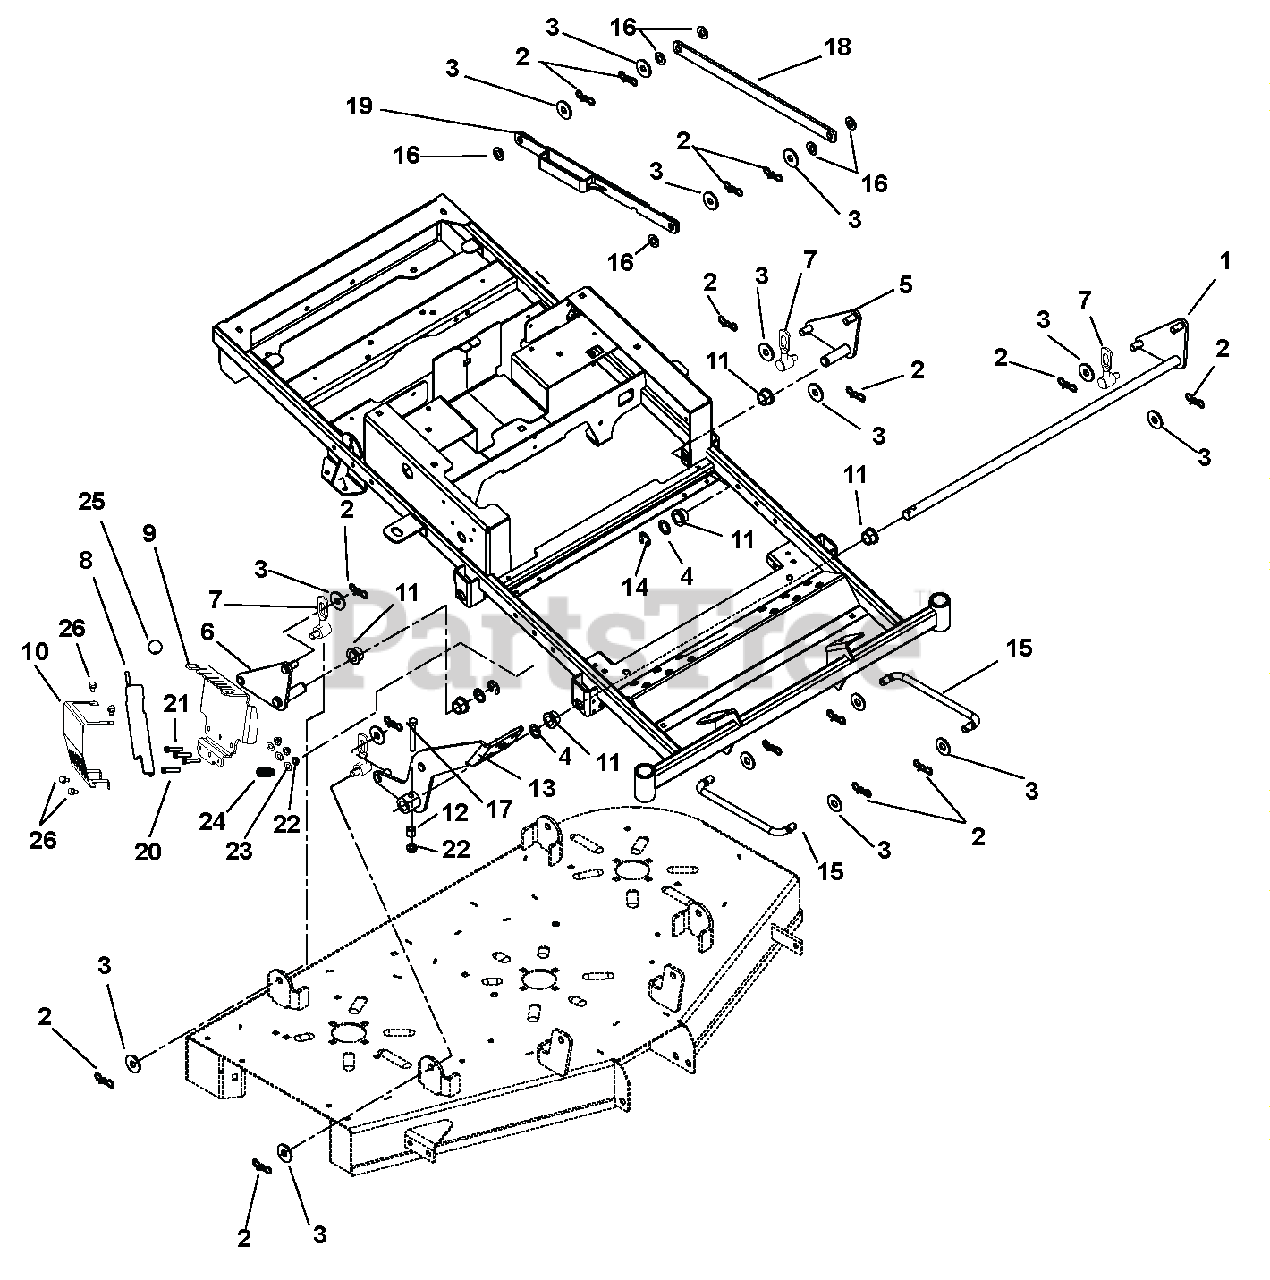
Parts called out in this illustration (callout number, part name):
1	WMT-DECK PIVOT FRONT
2	PIN,BOW TIE LOCKING .091X1.875
3	WSHR-FL-STL.511X1.441X.125 YWZ
4	WSHR-FL-STL.754X1.125X.062YWZC
5	WMT-DECK PIVOT ZTXL REAR LH
6	WMT-DECK PIVOT ZTXL REAR RH
7	ASM, DECK LINK
8	LEVER, HOC WLDMT XL
9	BRACKET, ADJUSTER HOC XL
10	GUARD, PLATE FIXED
11	BSHG-FLG .750X1.000X.625X1.250
12	BSHG-SLV .391X.688X.52 PM
13	WMT-ZTXL FOOT PEDAL
14	RG-RTNG-EXT .750X.050
15	LINK, DRAG
16	WSHR-FL-NYL .518X1.000X.080
17	@BLT-HEX .38-16X2.50 GR5 YWZC
18	LINK, LIFT
19	HOC, LINK RETAINING XL
20	@BLT-HEX .38-16X2.25 GR5 YWZC
21	@BLT-HEX .38-16X1.75 GR5 YWZC
22	@NUT-LK-NYL-FLG .38-16 YWZC
23	@WSHR-FL-STL.38X.875X.083 YWZC
24	SPRING, COMPRESSION
25	KNOB,BALL -BLACK 1.47" .375-16
26	SCR-TAP .25-20X.50 HWH TR YWZ
